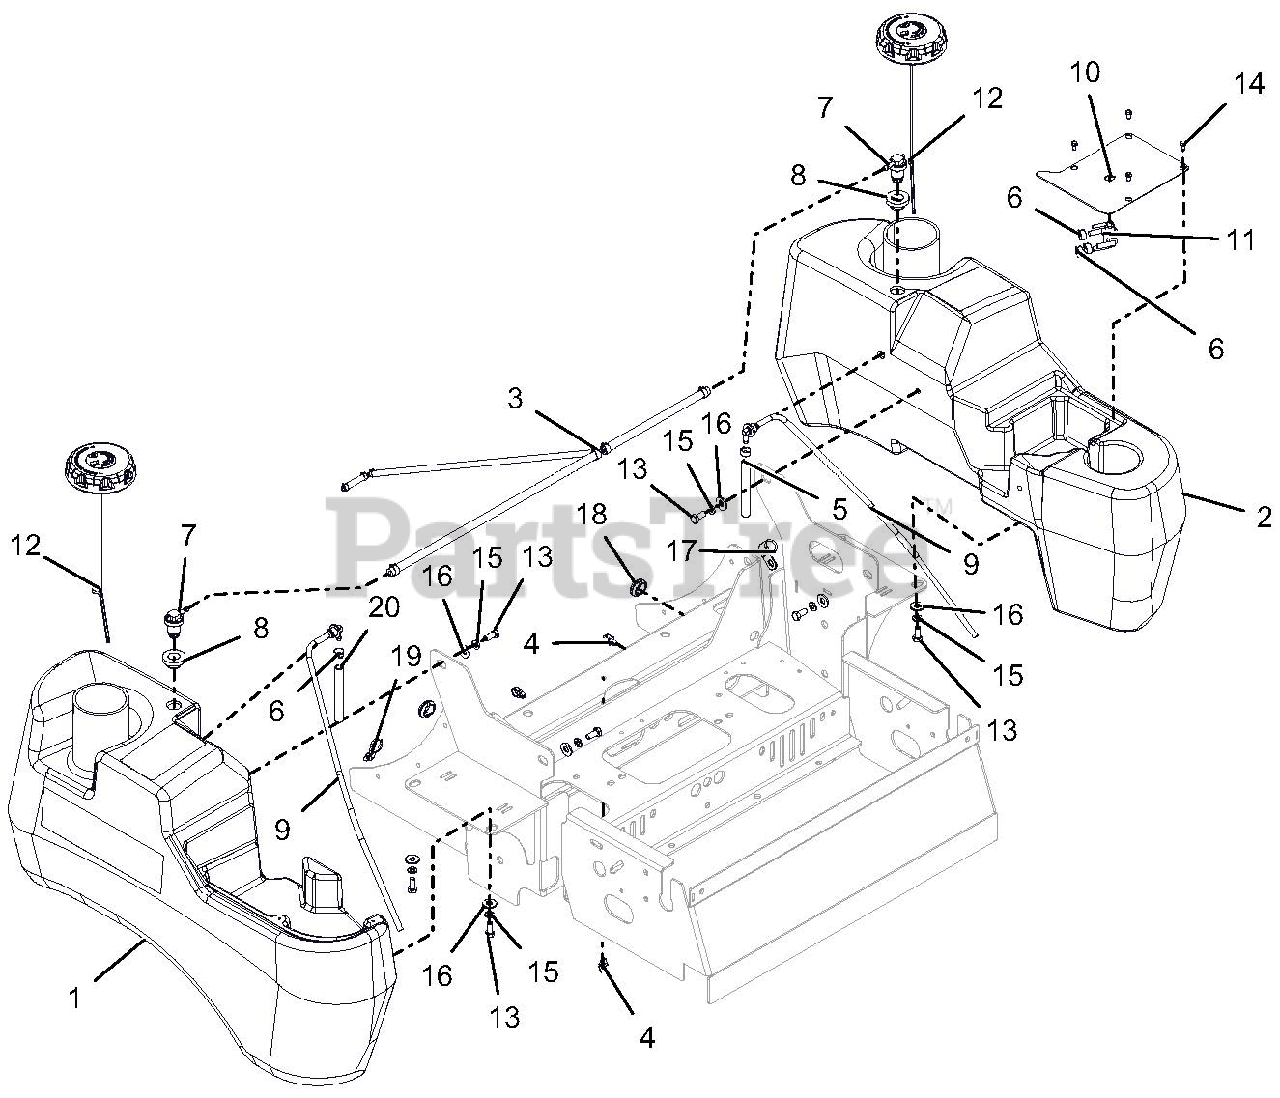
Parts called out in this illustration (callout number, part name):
1	TANK, RH LARGE GRAVELY FUEL
2	TANK, LH LARGE GRAVELY FUEL
3	ASM, PT400 FUEL LINE
4	CLIP, ROUTING .50 ID
5	.25 LOW-PERM GAS HOSE 19.00" LG - LH TANK TO VALVE
6	CLAMP, FUEL LINE
7	VALVE, 2-WAY
8	GROMMET, REMOTE VENT NITRILE
9	ASM, LARGE TANK FUEL PICKUP
10	PLATE, FUEL VALVE MOUNTING-RED
11	VALVE, FUEL
12	CAP, FUEL VENT-IN AUTOLOCK
13	BLT-HEX .31-18X.75 GR5 YWZC
14	SCR-MCH 10-24X.38 HWHSTAINLESS
15	WSHR-LK .31X.078 REG YWZC
16	WSHR-FL-STL.38X.875X.083 YWZC
17	CLAMP, CUSHIONED STEEL .75
18	GROMMET, RUBBER
19	CABLE TIE W/ TREE, .25 HOLE
20	.25 LOW-PERM GAS HOSE 54.00" LG - RH TANK TO VALVE
